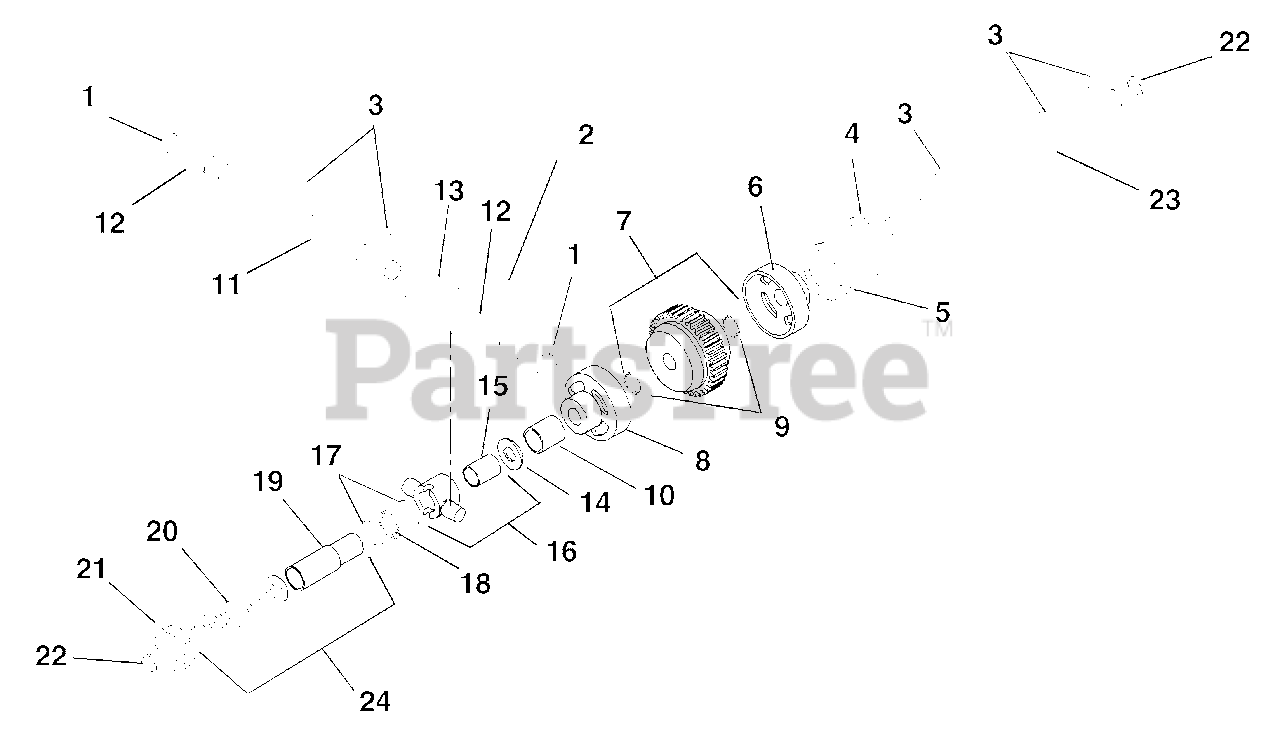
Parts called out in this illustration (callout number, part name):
1	Ring-Retaining-External .57 x .05
2	Lever,PTO
3	Key-Woodruff .19 x .75
4	Ring-Retaining-External 1.38 x 1.30
5	Bearing-Ball 1.38 x 2.44 x .55
6	Cup, Clutch
7	Assembly, Clutch Cone Bearing
8	Cup, Clutch
9	Bearing-Roller .75 x 1.00 x .50
10	Bushing-Sleeve Steel .891 x 1.00 x 1.21
11	Shaft, PTO Yoke
12	O-Ring .63 x .75 x .062
13	Yoke, PTO
14	Washer-Hardened-Thrust .76 x 1.25 x .094
15	Bushing-Sleeve 1.00 x 1.12 x 1.00
16	Assembly, Shifting Collar
17	Washer-Thrust 1.55 x 1.00 x .093
18	Bearing-Needle-Thrust 1.00 x 1.55 x .078
19	Sleeve, PTO Throw-Out
20	Spring-Compression .19 x 5.50
21	Gear, Spur PTO 10 Diametral Pitch 22 Teeth
22	Ring-Retaining .70 x .93
23	Shaft, PTO Clutch
24	Kit, Sleeve and Spring
